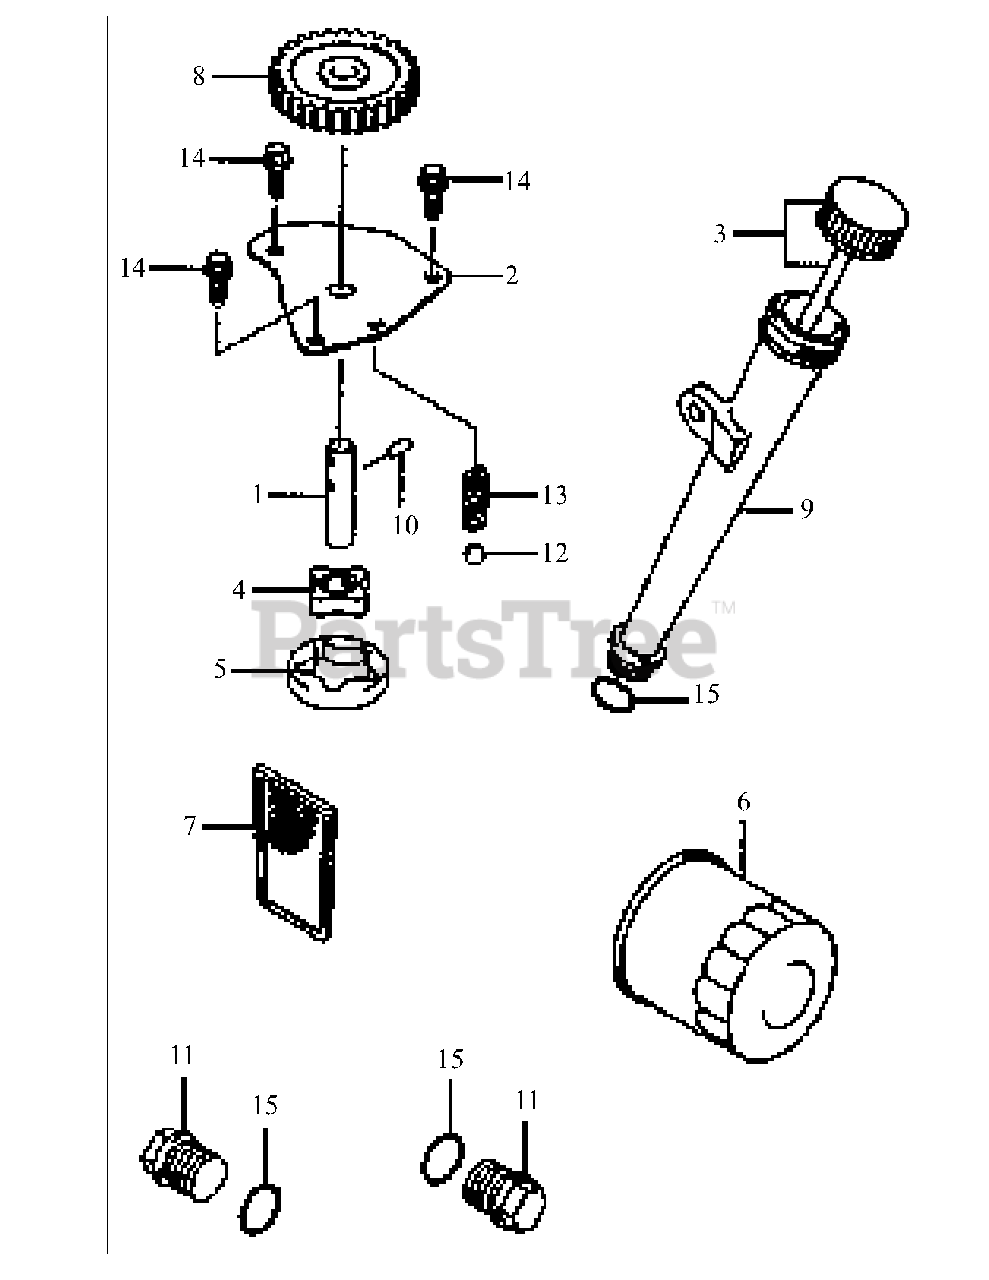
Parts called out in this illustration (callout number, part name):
1	Shaft, Oil Pump
3	Cap, Assembly
4	Rotor, Pump In
5	Rotor, Pump Out
6	Filter, Oil
7	Filter, Oil Screen
8	Gear, Spur
10	Pin
11	Plug
14	Bolt, Flange
